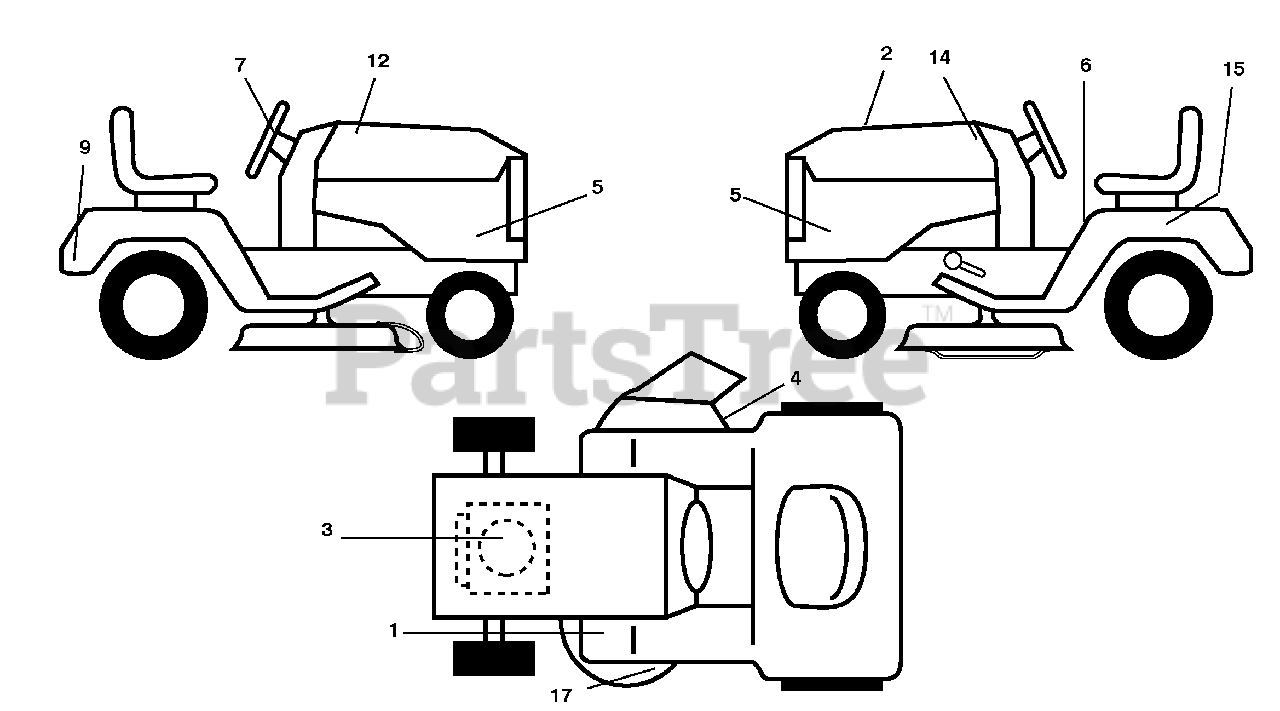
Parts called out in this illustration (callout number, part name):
2	Decal, Replacement
3	Decal, Engine HP
4	Decal, Warning
5	Decal, SDPNL
6	Decal, Fender Danger English
7	Decal, Ins Str Wh
9	Decal, Fender
12	Decal, Hood RH
14	Decal, Hood LH
15	Decal, Caution, Battery
17	Decal, V-Belt Sch.
17	Decal, Handle Lft Height Adj.
17	Manual, Operator's E&F
17	Manual, Parts E&F
